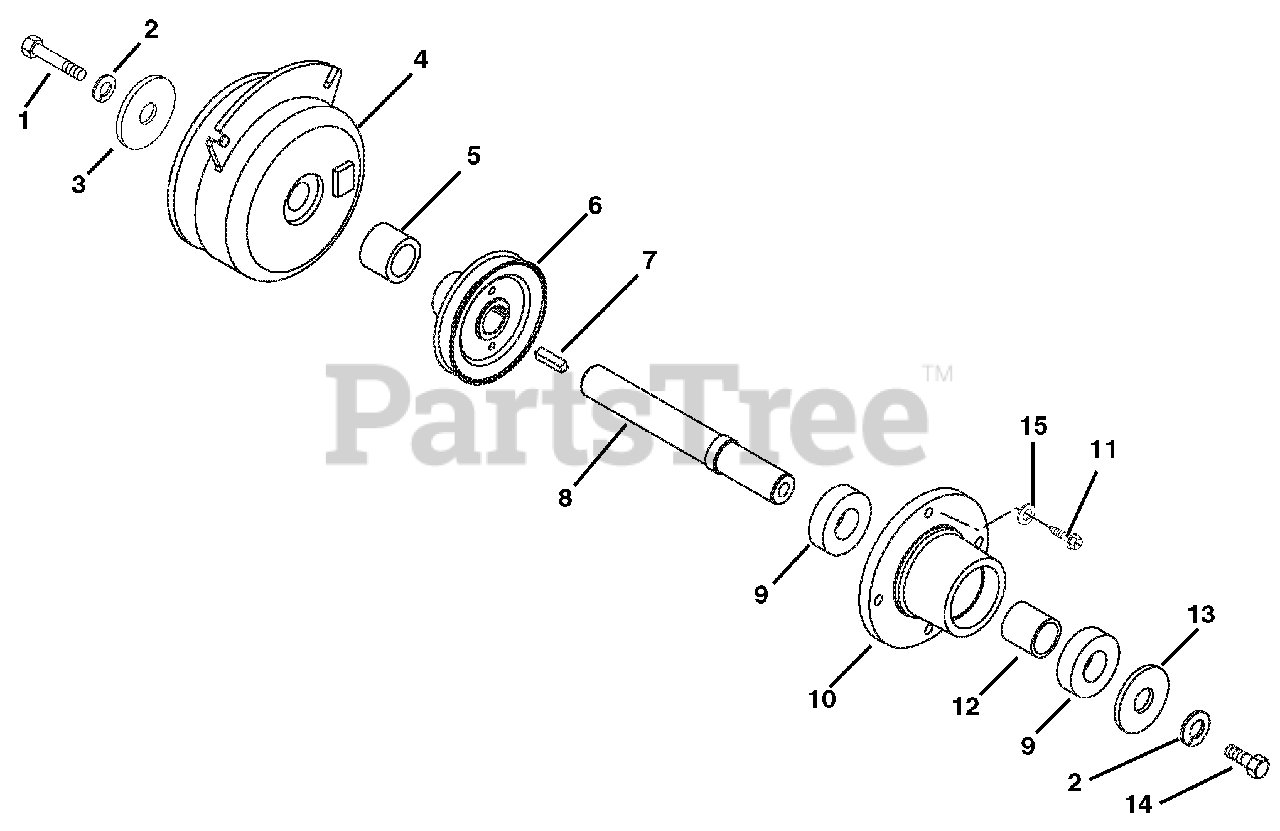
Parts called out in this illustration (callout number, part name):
1	Bolt-Hex .44-20 x 1.50 Grade 5
1	Bolt-Hex .44-20 x 2.50 Grade 5
2	Washer-Locking .44 x .109
3	Washer-Flat-Steel .469 x 2.00 x .25
4	Clutch-Electric/Brake
5	Spacer 1.004 x 1.500 x .740
6	Sheave-Jackshaft 4.50
6	Sheave- Jackshaft 4.50
7	Key-Square .25 x 1.00 x .25 SAE
7	Key-Square .25 x .625 x .25 SAE 8630 OR SAE 1035
8	Shaft-Jack
9	Bearing-Ball .984 x 2.04 x .59
10	Housing-Transmission Spindle
11	Screw-Tapping .31-18 x .75 Hex Washer Head
12	Spacer 1.00 x .253 x 1.26
13	Washer-Flat-Steel .463 x 1.38 x .25
14	Bolt-Hex .44-20 x 1.00 Grade 5
15	Washer-Flat-Steel .328 x 1.00 x .094
